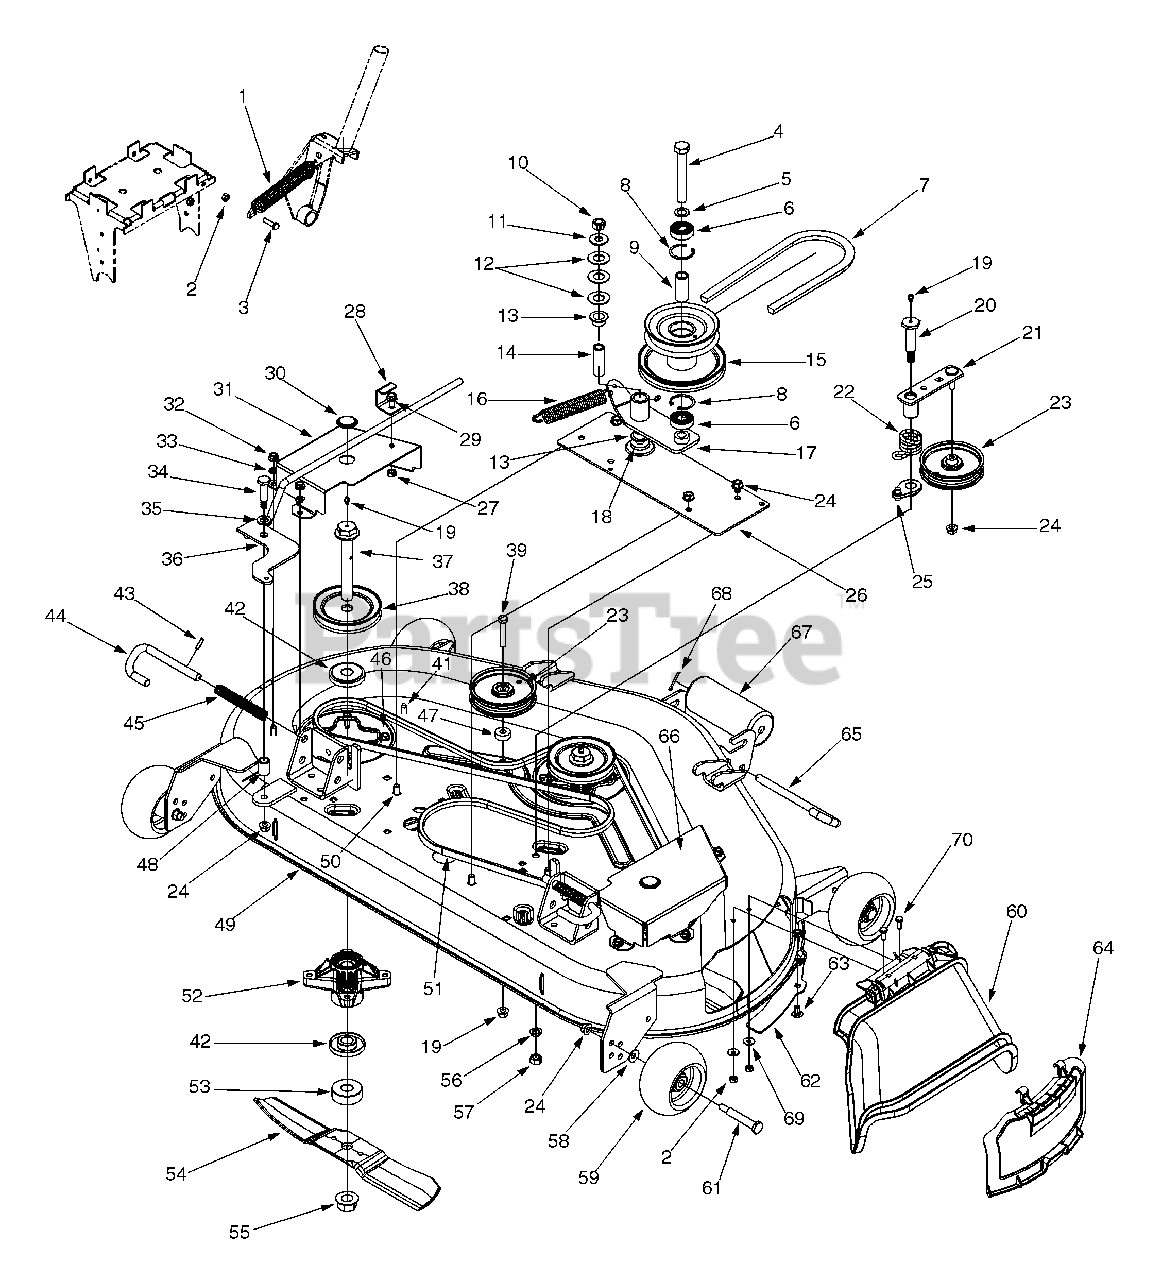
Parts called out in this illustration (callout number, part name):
1	Extension Spring .94 OD x 7.57
2	Hex Nut 1/4-20
3	Hex Cap Screw 1/4-20 x 1.0
4	Hex Cap Screw 5/8-18 x 4.25
5	Flat Washer 5/8 ID x 1.0 OD
6	Bearing .625 ID x 1.574 OD
8	Snap Ring
9	Spacer .635 ID x 2.0
10	Hex Lock Nut 1/2-20
11	Flat Washer 1/2 x 1.25
12	Flat Washer .76 ID x 1.49 OD
13	Flange Bearing 3/4 ID x .52
14	Spacer .50 OD x .75 ID
15	Pulley
16	Extension Spring 1.0 OD x 6.140
17	Idler Assembly
18	Flat Washer .531 ID x 1.25 OD
19	Grease Fitting
20	Shoulder Screw
22	Torsion Spring
23	Flat Pulley
24	Flange Lock Nut 3/8-16
25	Retainer Spring
26	Deck Mounting Plate Assembly
27	Flange Lock Nut 5/16-18
29	Hex Cap Screw 5/16-18 x .75
30	Button Plug
32	Hex Nut 5/16-18
33	Lock Washer 5/16
34	Shoulder Screw .498 x 1.445
35	Flat Washer .531 x .93
38	Pulley
39	Hex Cap Screw 3/8-16 x 2.0
41	Screw 5/16-18 x .750
42	Spindle Spacer
44	Support Pin
45	Compression Spring .63 OD x 6.3
46	Hex Washer Screw 5/16-18 x .750
47	Spacer .406 ID x 1.0 OD
48	Spacer .550 ID x .750 OD
52	Spindle Assembly
53	Blade Spacer
54	Blade
55	Hex Flange Nut 3/4-16
56	Lock Washer 7/16
57	Hex Nut 7/16-14
58	Bell Washer .401 ID x .870 OD
59	Deck Wheel
60	Chute Assembly
61	Shoulder Screw 1/2 x 2.5
63	Carriage Bolt 5/16-18 x .62
64	Mulching Plug
65	Roller Pin
67	Front Roller
68	Pin
69	Bell Washer .265 ID x .75 OD
70	Hex Cap Screw 1/4-20 x .620
